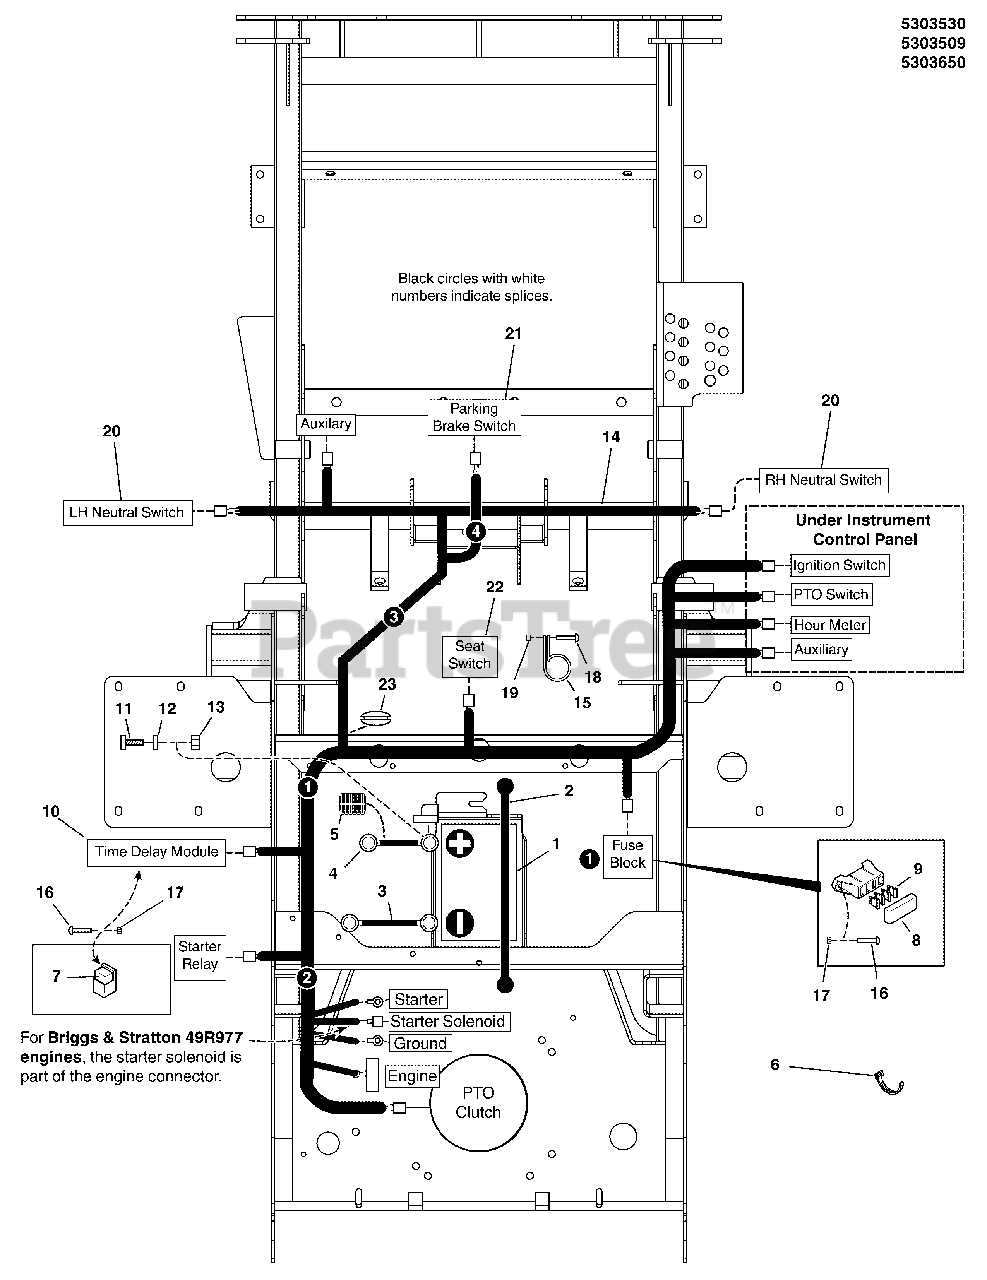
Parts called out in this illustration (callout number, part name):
1	BATTERY, WET ( BCIU1, 350 CCA)
2	STRAP-BLACK RUBB
3	BATTERY CABLE, NEG, 14, 5/16-13/32
4	BATTERY CABLE, POS, 22, 1/4-5/16
5	WIRE LOOM, 3/8 ID X 16 IN
6	TIE, SELF-LOCKING, 12"
7	RELAY, 12V, 40A
8	COVER, VINYL FUSEBLOCK
9	FUSE, ATO, 20 AMP
9	FUSE, ATO-15 (15 AMP)
10	MODULE, TIME DELAY
11	BOLT, 1/4-20 X 3/4 GD5 YZ
12	WASHER, 1/4 SAE
13	NUT, 1/4-20 HEX SERR. FLANGE
14	WIRE HARNESS, M49 VANGUARD, IS2100Z
14	WIRE HARNESS, BV32, IS2100Z
15	CLAMP, VINYL INSULATED
16	SCREW, #10-24 X 3/4 ROUND PHILLIPS
17	NUT, #10-24 HEX NYLON LOCK
18	SCREW,1/4-20X1,ZINC PHOS & OIL
19	NUT,1/4-20,GR5,HEX,ZC/CL
20	SWITCH, PLUNGER, NO, SINGLE POLE SNAP-IN
21	SWITCH, LOW PROF, NC/NO
22	SWITCH, PLUNGER, N.C.
23	GROMMET, 1-1/2" ID FOR 1/4 METAL
